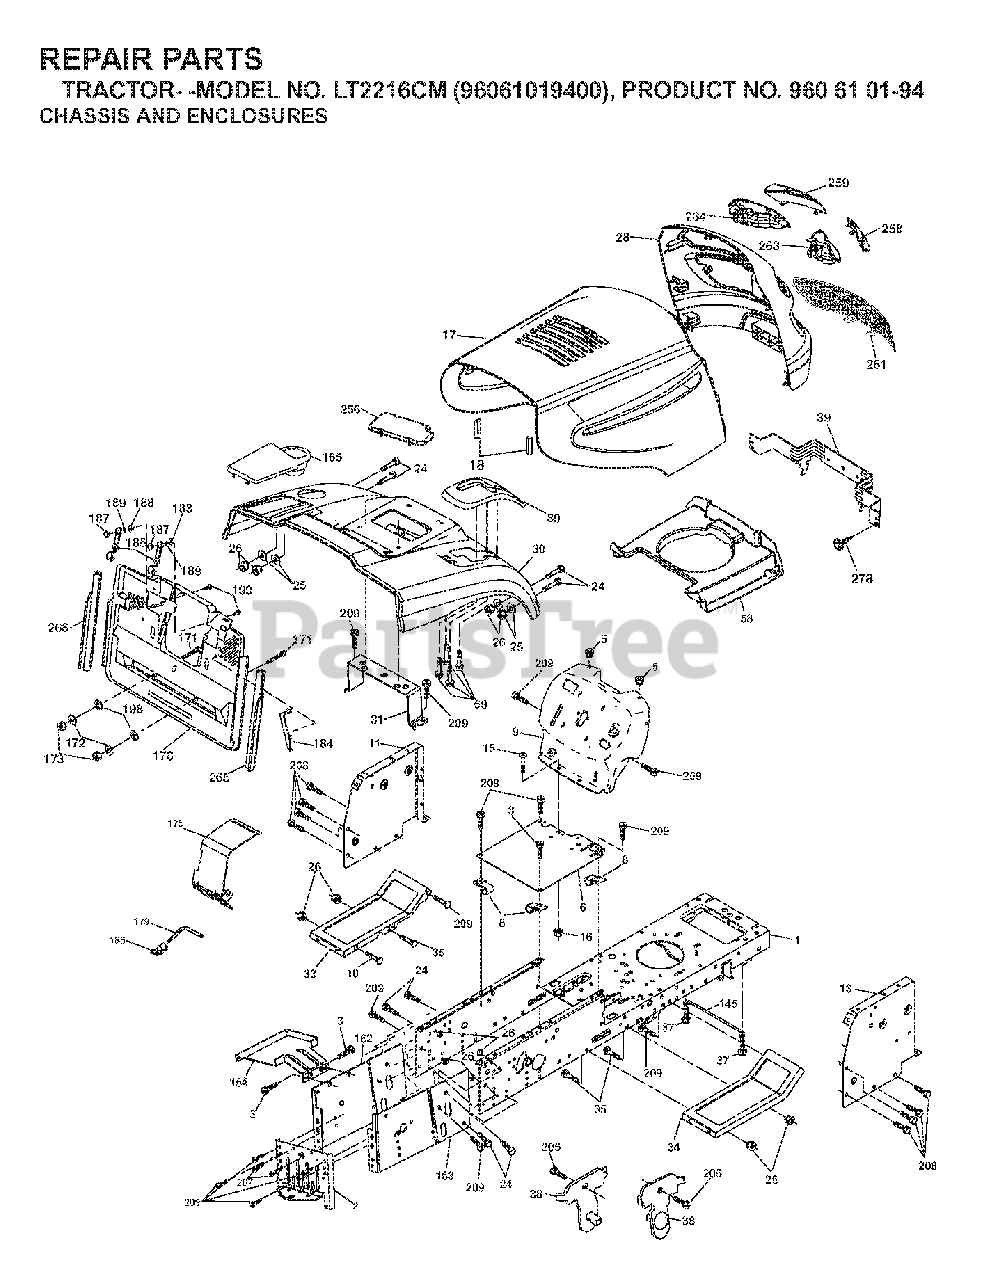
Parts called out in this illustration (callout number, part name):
1	CHASSIS
3	SCREW 3/8-16X3/4
5	BUMPER.RUBBER.HOOD
8	CLIP,INSULATOR
10	BOLT D
11	PANEL.DASH.LH.LTX
13	PANEL DASH RH
16	NUT
18	BUMPER.HOOD.LARGE.1.75"
25	WASHER
26	NUT
31	BRACKET SUPPORT FENDER
33	FOOTREST - LH
34	FOOTREST, RH
39	BRACKET PIVOT
69	SCREW.HI-LO.CONSOLE
145	ROD PIVOT CHASSIS/HOOD
164	SUPPORT
171	BOLT
172	WASHER
186	LATCH ASSY
187	WELDNUT
189	LOCKWASHER
207	SCREW, 5/16-18 X 1/2
208	SCREW 3/8-16X1/2
209	SCREW, 3/8-16X3/4
263	BEZEL GRILL RH
264	BEZEL GRILL LH
278	SCREW
